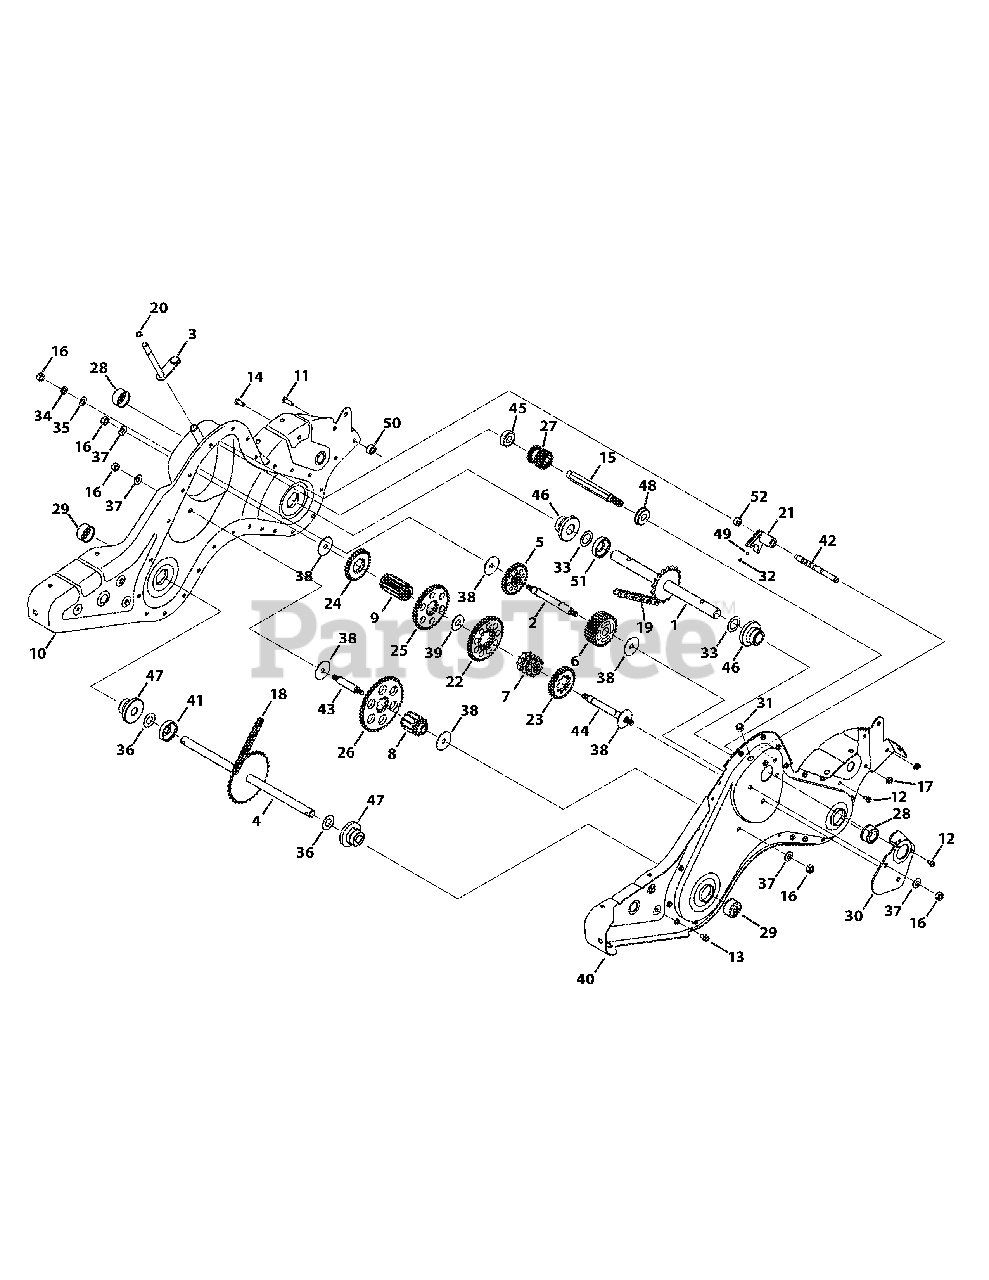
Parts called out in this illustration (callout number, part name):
1	Shaft Assembly, Tine, 18T
2	Shaft Assembly, Jack
3	Shaft Assembly, Shift Input
4	Shaft Assembly, Wheel, 33T
5	Gear Assembly, 30T Reverse Idler
6	Gear Assembly, 30T Tine Idler
7	Sprocket Assembly, 9T Tine Input
8	Sprocket Assembly, 10T Wheel Input
9	Gear Assembly, 11T
10	RH Chain Case Housing Assembly
11	Hex Head Screw, 5/16-18 x 1.00
12	Screw, 1/4-20 x 0.500
13	Screw, :5/16-18 x 0.625
14	Hex Head Screw, 5/16-18 x .75
15	Input Shaft, .75
16	Nut, Hex, 7/16-20
17	Nut, Flangelock, 5/16-18
18	Endless Chain, #420 x 50 Links
19	Endless Chain, #50 x 54 Links
20	Snap Ring, .500
21	Clutch Collar
22	Gear Spur, 44T
23	Gear Spur, 30T
24	Gear Spur, 30T
25	Gear Spur, 44T
26	Gear Spur, 44T
27	Gear Spur, 16T
28	Shaft Seal, 1.0
29	Shaft Seal, .75
30	Positioner Gear Bracket
31	Tapered Cap Plug
32	Compression Spring, .230 OD
33	Washer, Flat, 1.03 x 1.62 x .03
34	Washer, Lock, 7/16
35	Washer, Flat,.474 x .879 x .064
36	Washer, Flat, .760 ID x 1.50 OD
37	Washer, Bell,.45 x 1.00 x .062
38	Washer, Thrust, .445 x 1.92 x .060
39	Washer, Flat,1.595 x .635 x .062
40	LH Chain Case Housing
41	Spacer, .75 x 2.0 x .50
42	Shaft Detent, .5 DIA
43	Shaft, Jack, .625 x 2.385
44	Shaft, Jack, .6250 x 5.0050
45	Ball Bearing, 17 x 40 x 12:6203
46	Flange Bearing, 1.0 x 2.5 x 1.38
47	Flange Bearing, .75 x 2.5 x 1.38
48	Ball Bearing, 17 x 40 x 12:6203
49	Ball, Detent, .250
50	Spacer, .315 x .750 x .375 LG
51	Spacer, 1.0 ID x 2.0 OD x.5 LG
52	Spacer, .505 ID x .88 OD x .440
